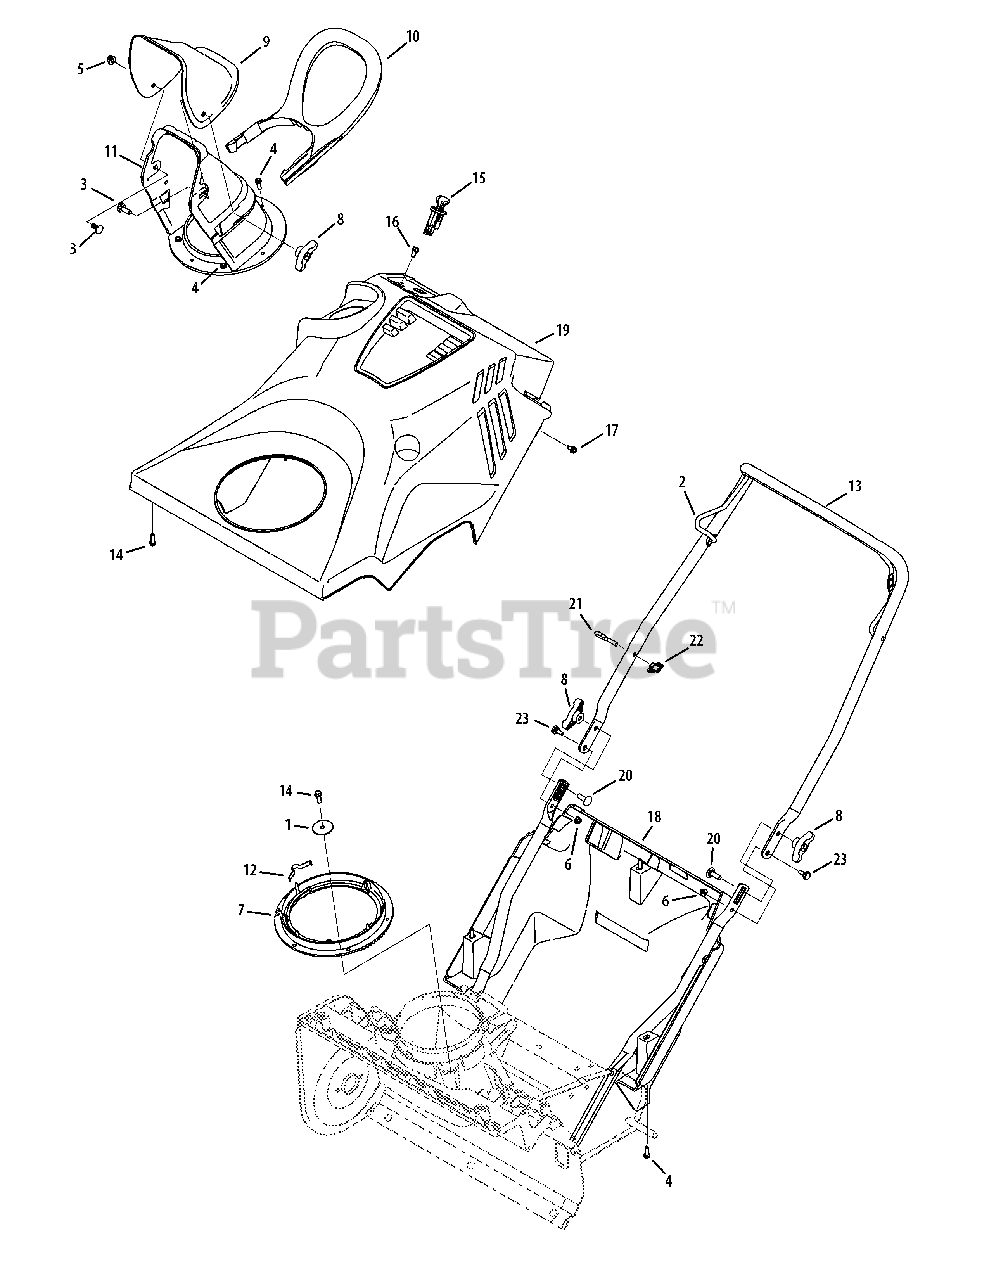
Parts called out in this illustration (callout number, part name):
1	Flat Washer, .28 x 1.5 x .075
3	Carriage Bolt, 5/16-18 x .750
4	Hex Washer Screw, 1/4 x .750
5	Flange Lock Nut, 5/16-18
6	Flange Lock Nut, 1/4-20
7	Chute Ring
8	Wing Knob, 5/16-18
9	Upper Chute
10	Chute Handle
11	Lower Chute
12	Chute Adjustment Spring
13	Upper Handle
14	Screw, Hi-Lo:1/4-15, 0.75
15	Ignition Switch Assembly
16	Hex Washer Screw, 1/4-15 x .50
17	Hex Washer Screw, 1/4-20 x .625
18	Bottom Cover
19	Top Cover
20	Carriage Screw, 5/16-18 x 1.00
21	Eye Bolt, 1/4-20
22	Handle Knob
23	Shoulder Screw, 1/4-20 x .375 x .148
